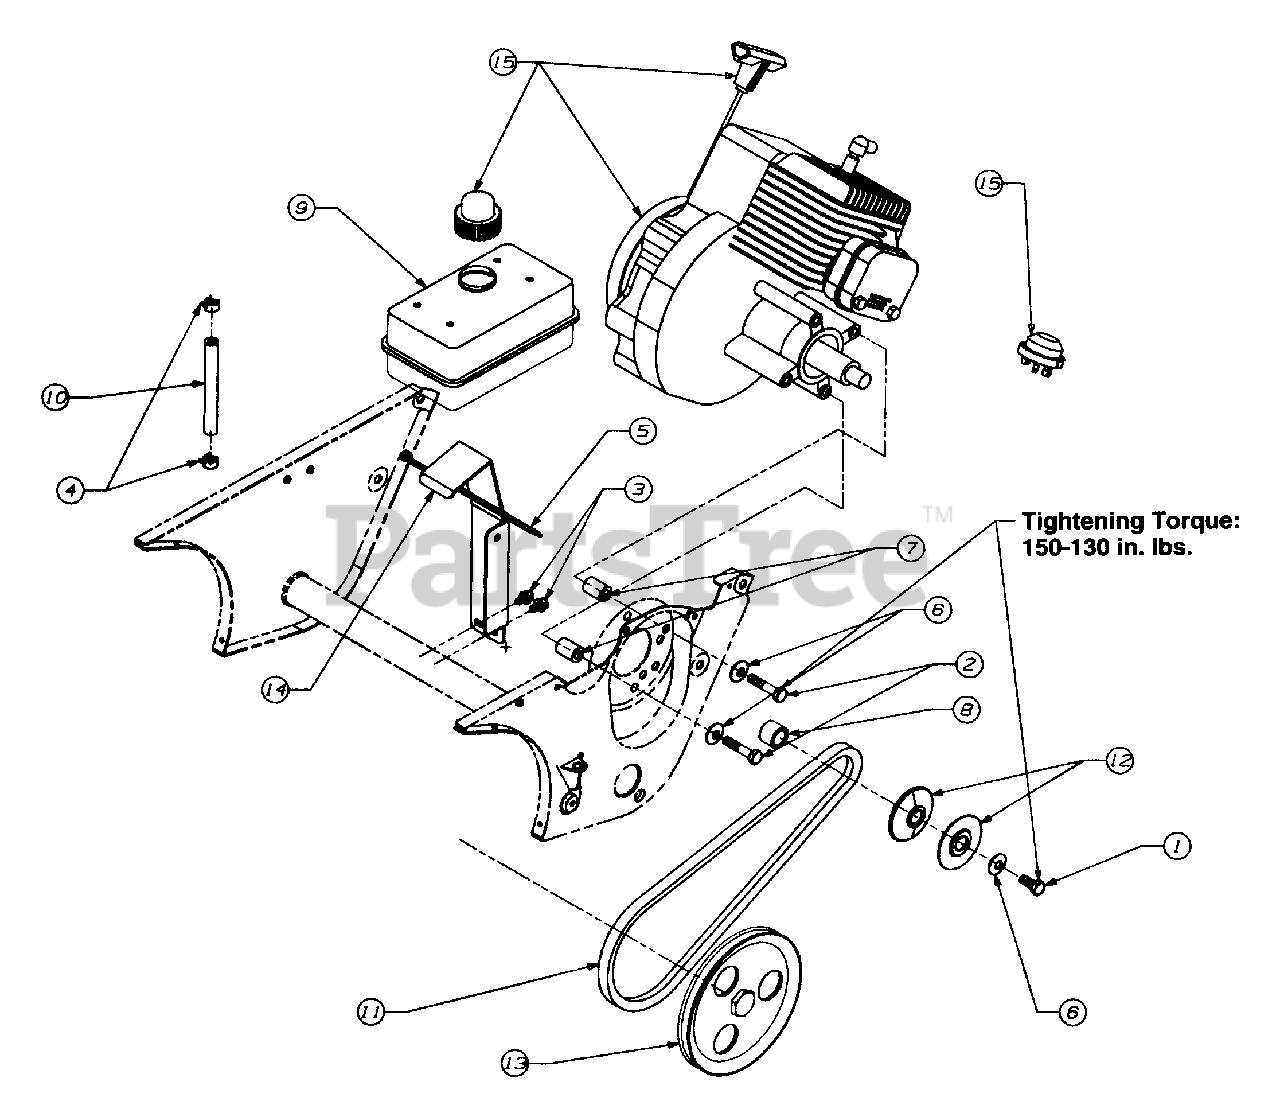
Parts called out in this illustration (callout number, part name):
1	Screw Hex
2	Screw Hex
3	Screw Hex
4	Clamp Hose
5	Tie Cable
6	Washer Bell
7	Spacer
8	Spacer
9	Tank-Gas (1 Qt.)
10	Hose-Fuel Line (12")
11	V-Belt
12	Pulley Half V
13	Pulley
